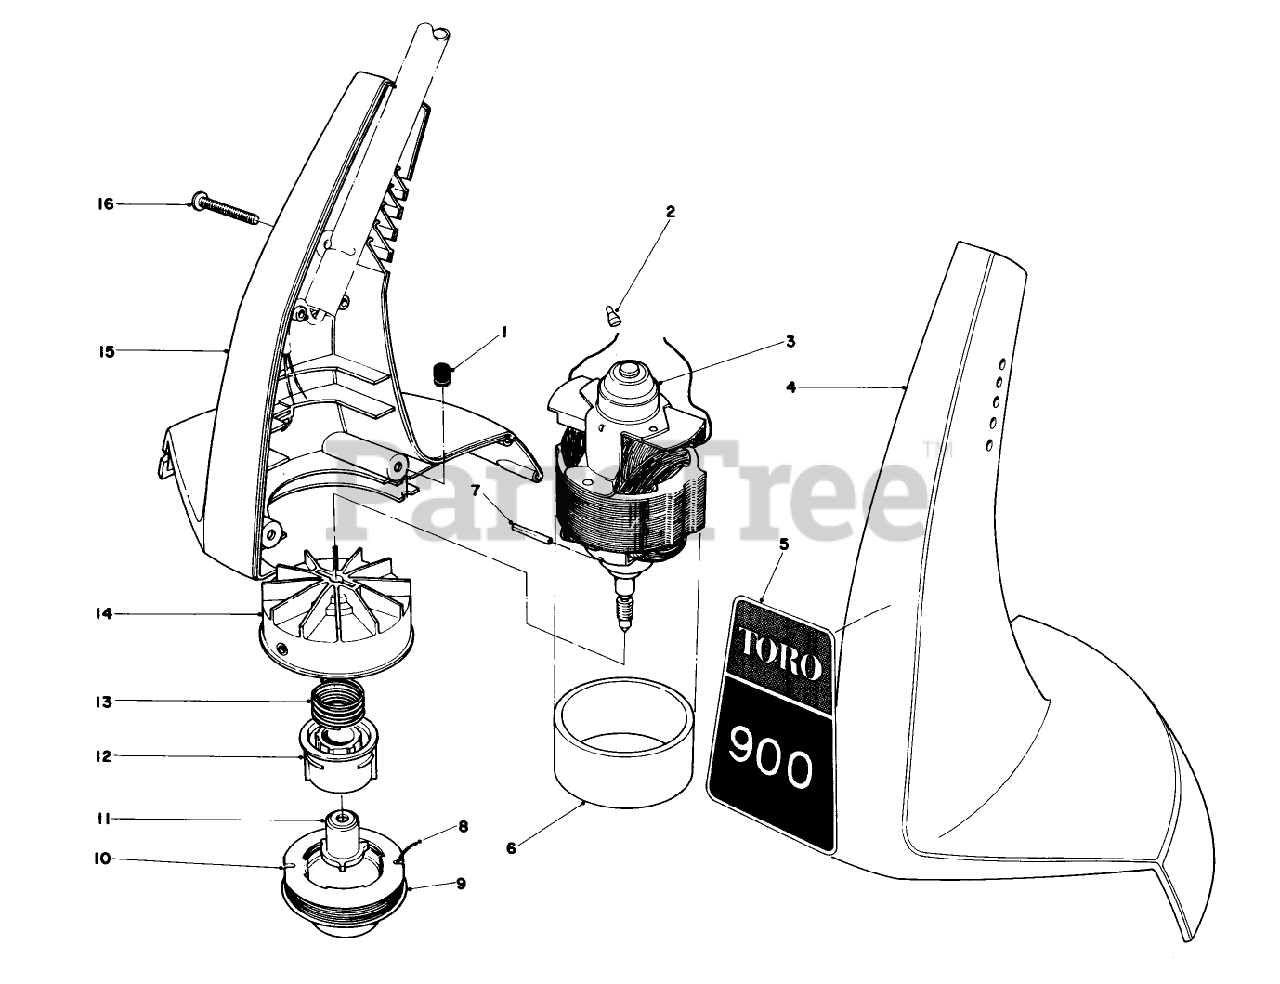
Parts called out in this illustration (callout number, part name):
1	GROMMET
2	CONNECTOR WIRE JOINT
3	Motor
4	Left Housing
5	Decal-900 Toro
6	DAMPENING SLEEVE
7	COIL PIN
8	.040" Cutting Line in Coil
9	SPOOL CAP
10	Prewound Spool
11	Driver
12	CORE - SPOOL
13	SPRING-COMPRESSION
14	FAN HUB ASM
15	Right Housing
16	Screw
